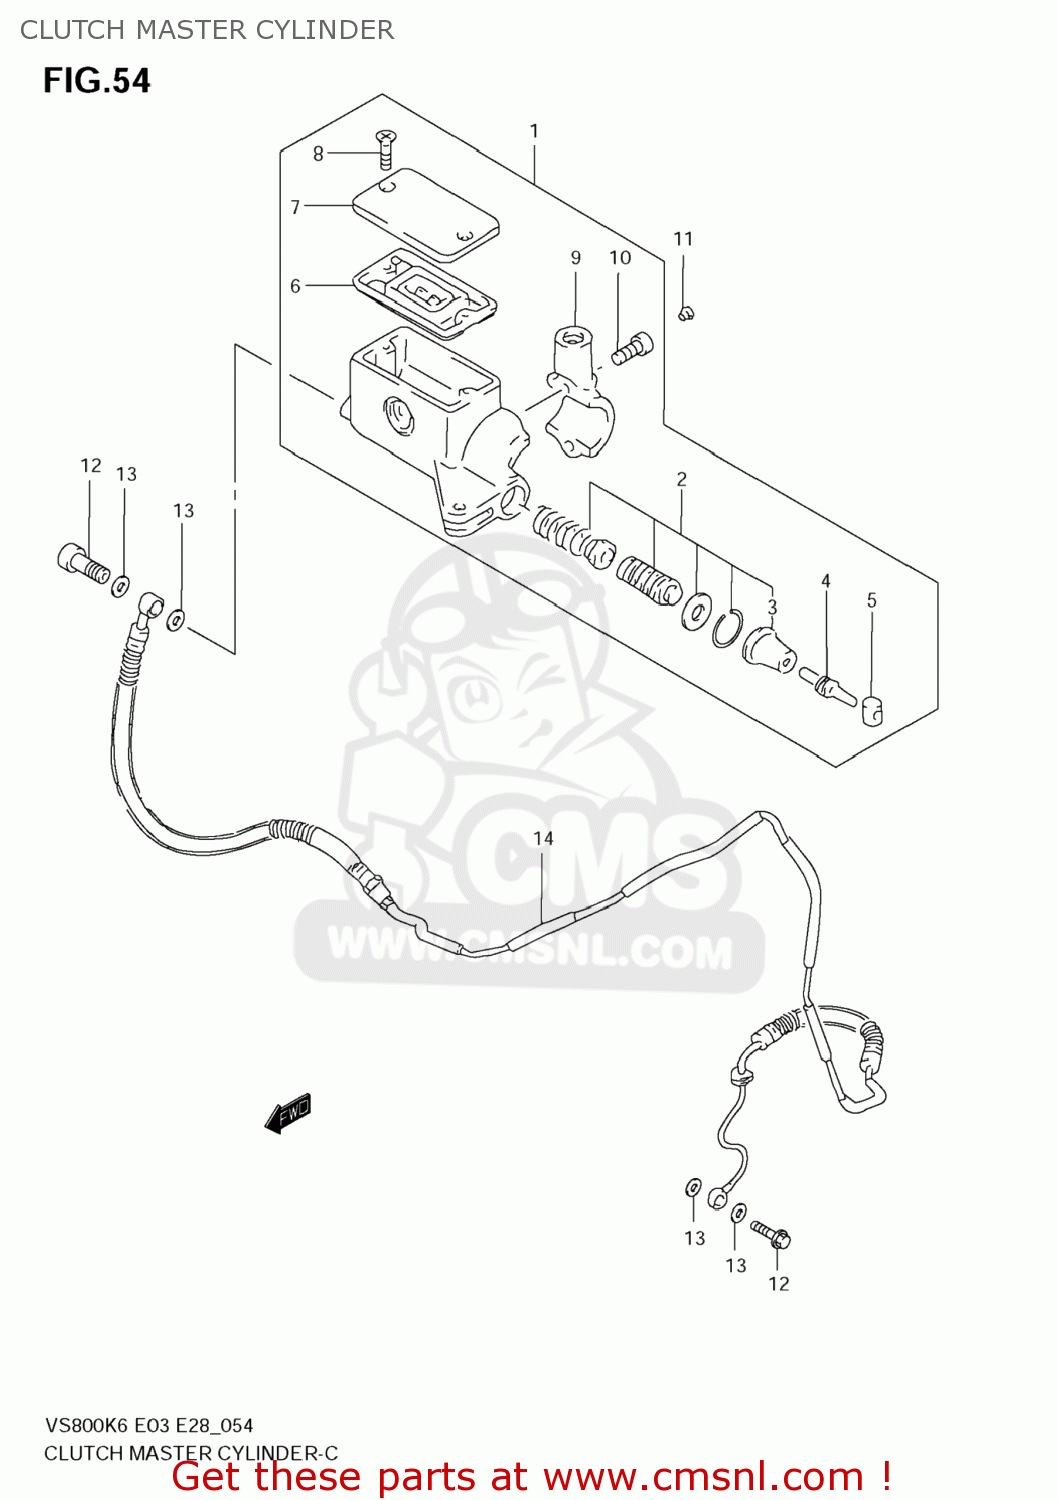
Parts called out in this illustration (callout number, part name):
1	CYLINDER ASSY, CLUTCH MASTER
2	PISTON & CUP SET
3	BOOT
4	PUSH ROD
5	BUSH
6	7
7	CAP
8	SCREW
9	HOLDER
10	BOLT
11	CAP(OD:10)
12	BOLT UNION
13	WASHER(10X15X1.5)
14	HOSE ASSY,CLUTCH
